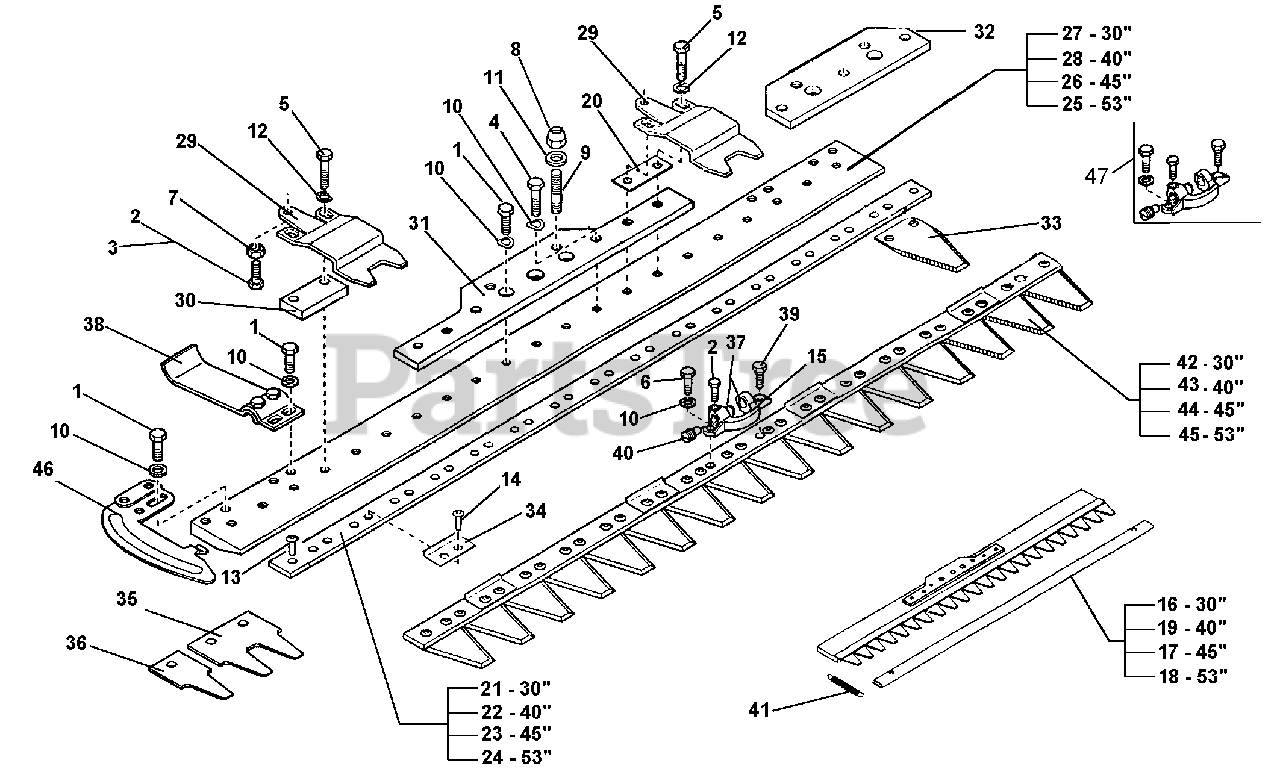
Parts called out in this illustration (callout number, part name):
1	SCREW, M8X16
2	SCREW, M8X20
3	SCREW, M8X25
4	SCREW, M8X30
5	SCREW, M8X35
6	SCREW, M8X1X16
8	SPECIAL NUT, M14
9	STUD, M14X1.5X44
10	SUPER WASHER, M8
11	SUPER WASHER, M14
12	WASHER, LOCK, M8.4
13	RIVET 5.3X14
14	RIVET 5.3X16
15	BLADE COUPLER
16	BLADE GUARD 30"
17	BLADE GUARD 45"
18	BLADE GUARD 53"
19	BLADE GUARD 40"
20	SPACER, BLADE ADJUSTER
21	BLADE STRIP, 30"
22	BLADE STRIP, 40"
23	BLADE STRIP, 45"
24	BLADE STRIP, 53"
25	SLIDE FOR CUTTER BAR 53"
26	SLIDE FOR CUTTER BAR 45"
27	SLIDE FOR CUTTER BAR 30"
28	SLIDE FOR CUTTER BAR 40"
29	BLADE HOLDER
30	BLADE GUIDE BLOCK
31	BAR COUPLING
32	BAR COUPLING (EARLY STYLE)
33	INDIVIDUAL BLADE, SERRATED
35	DOUBLE FINGER
36	SINGLE FINGER
37	BLADE PIN HOLDER
40	ADJUSTING SCREW
41	SPRING, BLADE GUARD
42	BLADE ASSEMBLY, SERATED, 30"
43	BLADE ASSEMBLY, SERATED, 40"
44	BLADE ASSEMBLY, SERATED, 45"
45	BLADE ASSEMBLY, SERATED, 53"
46	END GUARD, PAIR
47	BLADE COUPLER, COMPLETE
